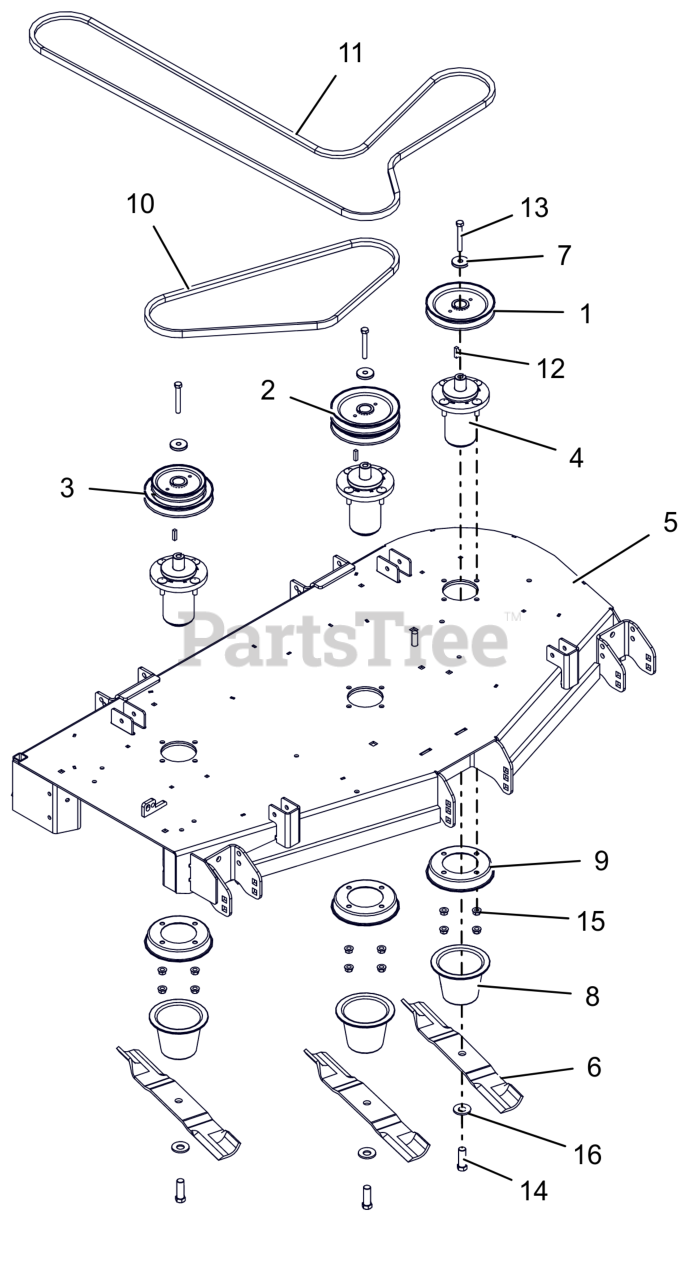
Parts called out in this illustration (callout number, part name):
1	PULLEY, SINGLE-1"ID X 6" OD
2	PULLEY, DOUBLE
3	PULLEY, DBL-1"IDX6.00"&4.75"OD
4	ASM, MAINT FREE ALUM SPINDLE
5	WLDMT, 52" SIDE DISCHARGE DECK-RED
6	BLADE, 18.00" MOWER (HI-LIFT)
7	RETAINER, SHEAVE
8	GUARD, SPINDLE LOWER
9	GUARD, SPINDLE TOP
10	V-BELT, B-COGGED
11	V-BELT, HB RAW EDGE EPDM
12	KEY, SQ .25X.25X1.00 RC 40-50
13	BLT, HEX .38-16X2.75 G8 ZCC
14	BLT, HEX .62-18X1.75 G8 ZCC
15	NUT-LK-CTR-FLG .375-16 GF ZCC
16	WSHR-BLVL .669X1.535X.138
